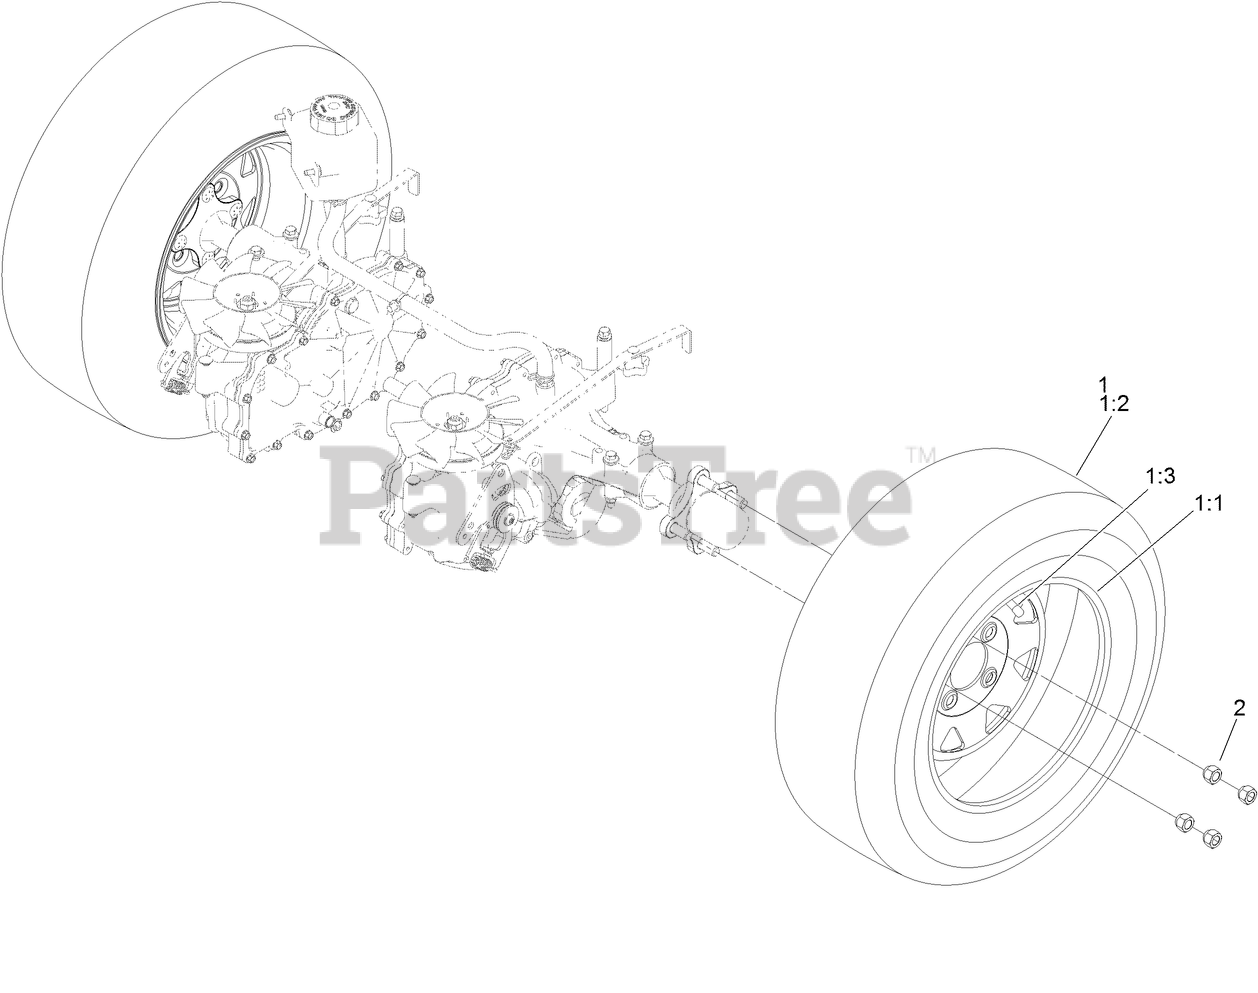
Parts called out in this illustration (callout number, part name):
1	WHEEL AND TIRE ASM
1:1	RIM-WHEEL
1:2	TIRE-DRIVE
2	NUT-LUG
